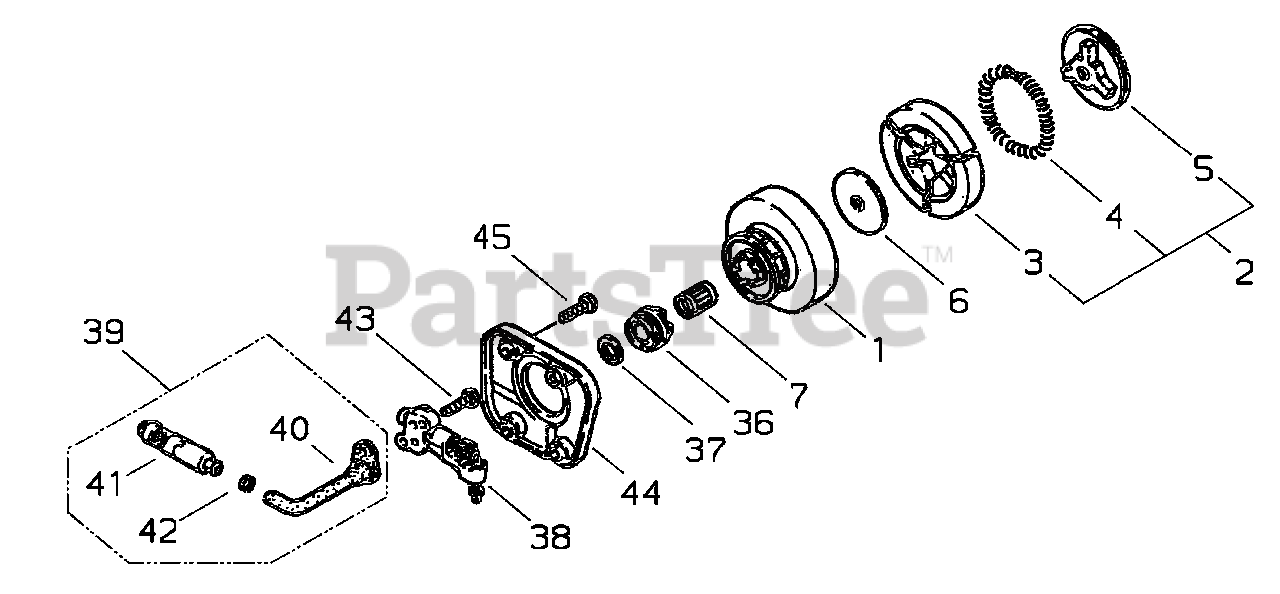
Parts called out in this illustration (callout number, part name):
1	DRUM, CLUTCH
2	CLUTCH ASSY
3	SHOE, CLUTCH
4	SPRING, CLUTCH
5	HUB, CLUTCH
6	WASHER, CLUTCH
7	BEARING, NEEDLE
36	GEAR
37	PLATE, THRUST
38	AUTO-OILER ASSY
39	PIPE ASSY
40	PIPE - OIL
41	FILTER, OIL
42	CLIP
43	SCREW - 4X12
44	COVER, PUMP
45	SCREW - 4X12
